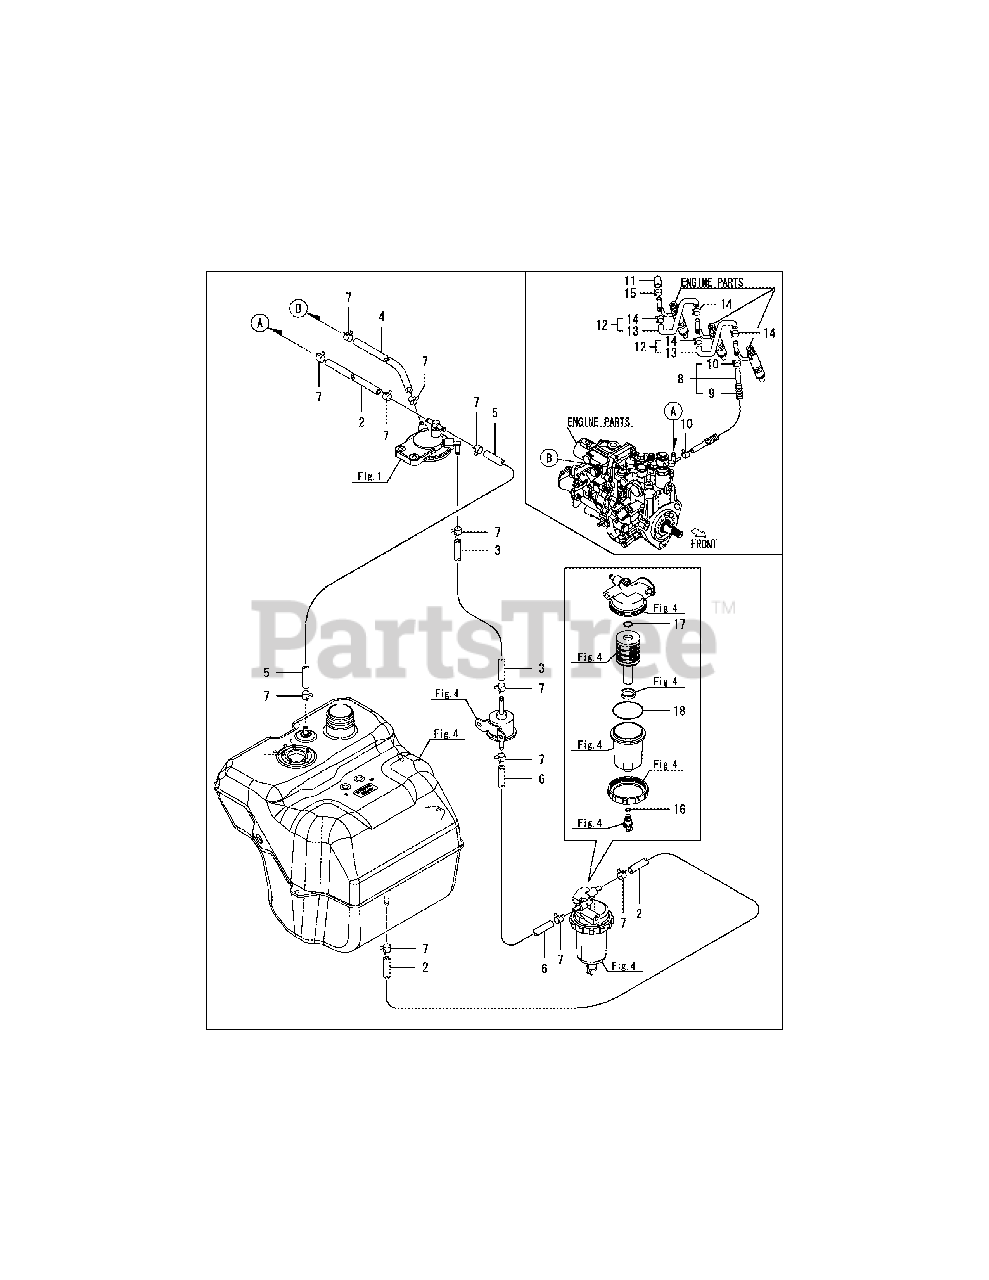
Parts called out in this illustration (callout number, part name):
2	HOSE, FUEL 35X350X35
3	HOSE, FUEL 70X45X270
4	HOSE, FUEL 40X290
5	HOSE, FUEL 33X650X33
6	HOSE, FUEL 70X70
8	PIPE ASSY, RETURN
9	PROTECTOR,HOSE
12	HOSE, FUEL RETURN
13	PIPE, FUEL RETURN
16	O-RING 4D P-7.0
17	O-RING 4D P-16.0
18	O-RING, 4D G65
